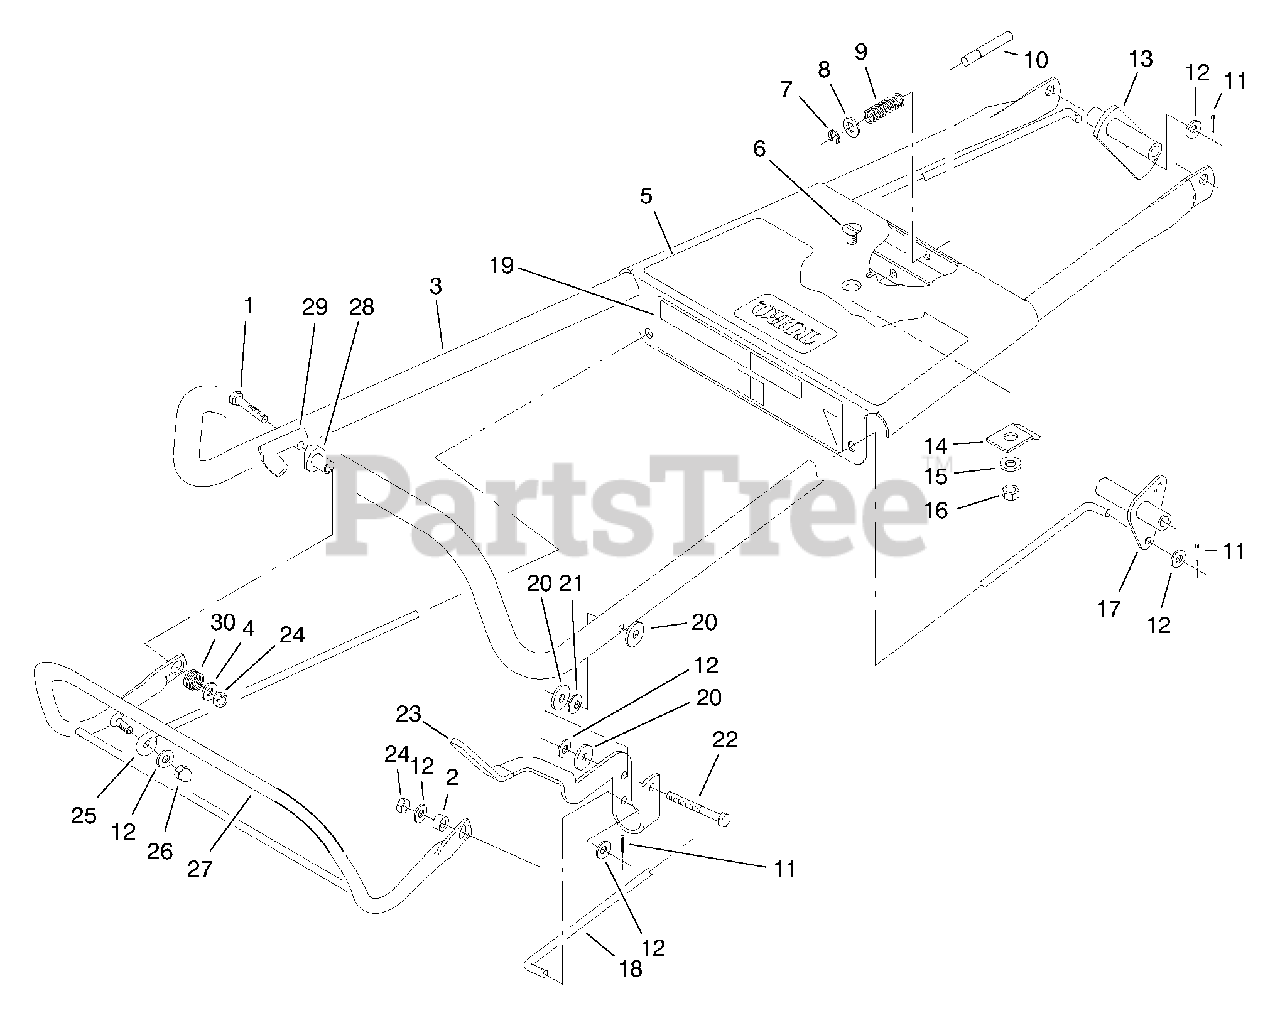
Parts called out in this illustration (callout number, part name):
1	Bolt-Carriage
2	Handle-Section Lower (Incl. Ref. #25)
3	Tie Strap
5	Screw-Hex Hd.
6	Nut-Lock
7	Screw-Phillips Hd.
8	Cam-Brake
9	Bracket-Bail Stop
12	Stop-Pivot
13	Bail-SP Control
14	Screw-Hex Hd. Cap
16	Cable-Throttle
18	Decal-Control Panel
20	Control-Speed Ground
21	Panel-Control (Incl. Ref. #18, & 24)
23	Bail-Engine Control
24	Decal-Console Front
25	Decal-Operation
26	Cable-Control
27	Clip-Rope Insert
28	Handle-Starter
29	Guide-Rope
30	Screw-Handle
31	Bracket-Cable Anchor
32	Nut-Lock
33	Handle-Upper
36	Bracket-Traction Cable
37	Cable-Traction
46	Screw-Hex Hd. Cap
49	Nut-Lock
51	Washer-Flat
